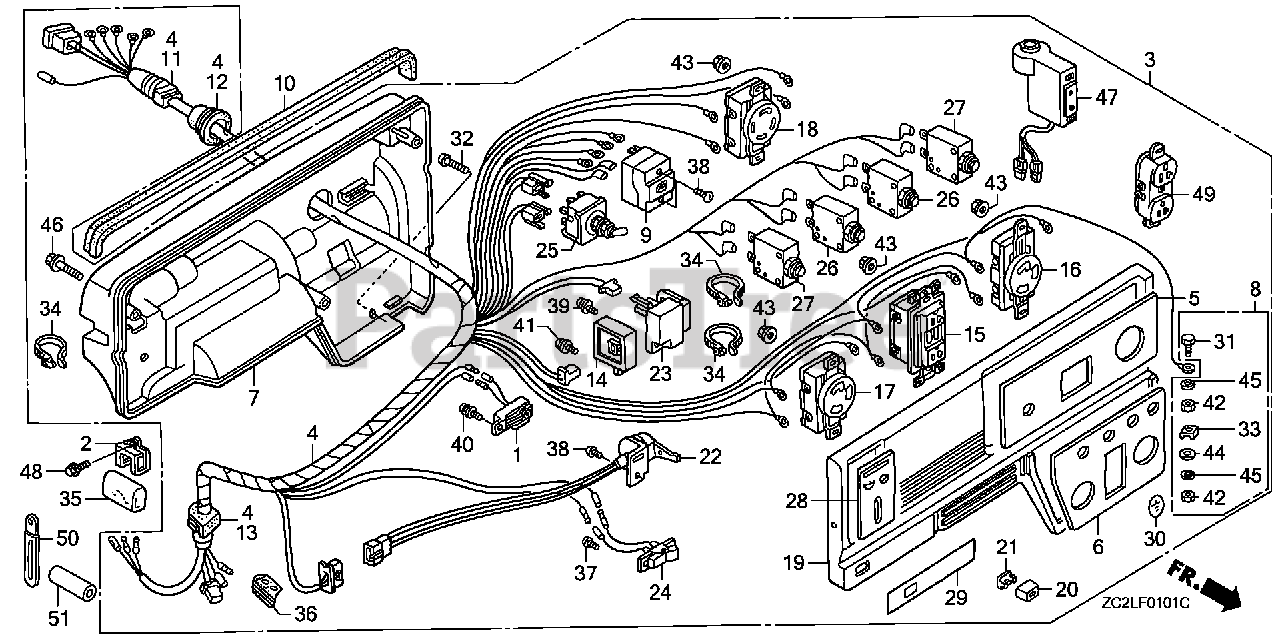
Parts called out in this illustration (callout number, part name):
3	BOX ASSY., CONTROL *R8* (BRIGHT RED)
3	BOX ASSY., CONTROL *R280* (POWER RED) (NOT AVAILABLE)
4	WIRE HARNESS ASSY. (NOT AVAILABLE)
5	MARK, SWITCH PANEL
6	MARK, A.C. OUT
7	CASE, CONTROL *R280* (POWER RED)
8	TERMINAL SET, GROUND
9	BREAKER, CIRCUIT (19A)
10	RUBBER, CONTROL
11	GROMMET, A.C. WIRE
12	GROMMET, MAIN WIRE
13	GROMMET, SWITCH WIRE
14	DIODE ASSY.
16	RECEPTACLE (20A/125V) (NOT AVAILABLE)
17	RECEPTACLE (30A/125V)
18	RECEPTACLE (30A/125-250V)
19	PANEL, CONTROL *R280* (POWER RED)
20	KNOB, PETCOCK LEVER
21	BUSH, CONTROL KNOB
22	SWITCH ASSY., ENGINE STOP
23	THROTTLE UNIT, AUTO (SAWAFUJI)
24	SWITCH, AUTO THROTTLE
25	SWITCH ASSY., VOLT CHANGE
26	PROTECTOR, CIRCUIT (20A)
27	PROTECTOR, CIRCUIT (30A)
28	MARK, ENGINE SWITCH
29	MARK, AUTO-THROTTLE
30	MARK, GROUND
31	BOLT, HEX. (6X28)
32	SCREW, GLOVE BOX
33	RETAINER (6MM)
34	TIE, CABLE (NATURAL 225X5.0)
36	GROMMET, TUBE
37	SCREW, PAN (3X6)
38	SCREW, PAN (4X6)
39	SCREW-WASHER (5X12)
41	SCREW-WASHER (4X12)
42	NUT, HEX. (6MM)
43	NUT, FLANGE (4MM)
44	WASHER, PLAIN (6MM)
45	WASHER, SPRING (6MM)
46	BOLT, FLANGE (6X40)
47	RELAY ASSY. (GFCI)
48	BOLT, FLANGE (6X12) (CT200)
49	RECEPTACLE (20A/125V) (MATSUSHITA)
50	CLIP, WIRE HARNESS
51	TUBE, CORD
